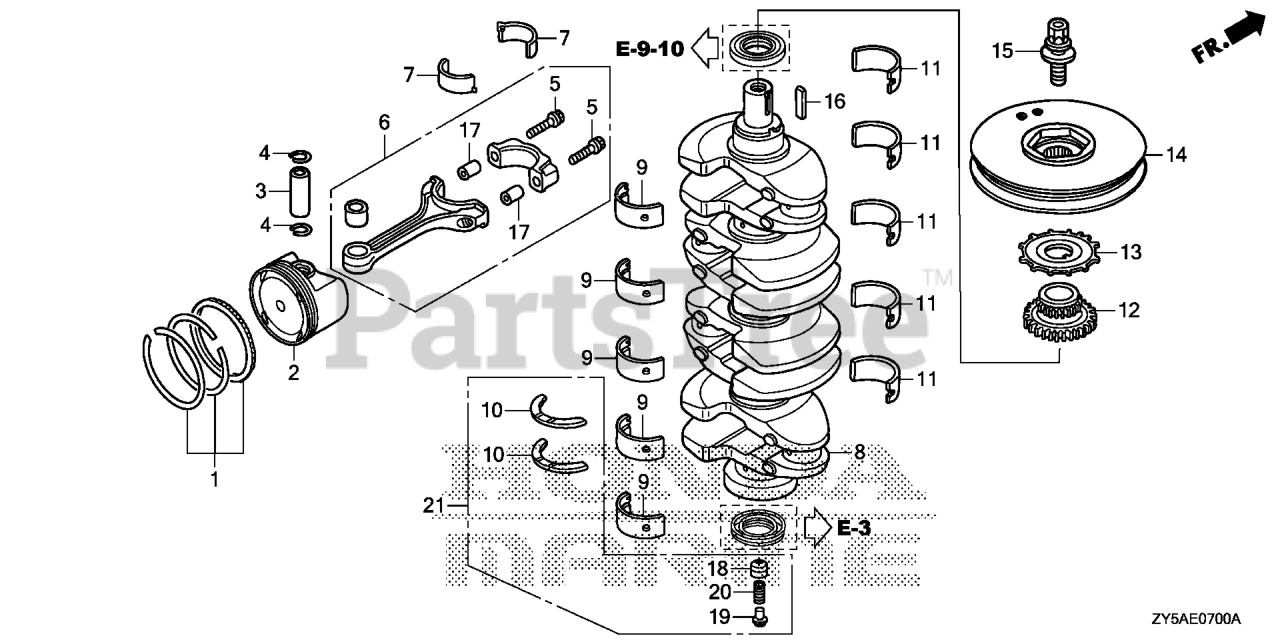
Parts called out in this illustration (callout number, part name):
1	RING SET, PISTON (STD)
3	PIN, PISTON
4	CLIP, PISTON PIN
5	BOLT, CONNECTING ROD (SOURCE: VINTAGE PARTS INC.)
6	ROD, CONNECTING
7	BEARING A, CONNECTING ROD (BLUE)
7	BEARING B, CONNECTING ROD (BLACK)
7	BEARING C, CONNECTING ROD (BROWN)
7	BEARING D, CONNECTING ROD (GREEN)
7	BEARING E, CONNECTING ROD (YELLOW)
7	BEARING F, CONNECTING ROD (PINK)
7	BEARING G, CONNECTING ROD (RED)
8	CRANKSHAFT
9	BEARING A, MAIN (UPPER) (BLUE) (DAIDO)
9	BEARING B, MAIN (UPPER) (BLACK) (DAIDO)
9	BEARING C, MAIN (UPPER) (BROWN) (DAIDO)
9	BEARING D, MAIN (UPPER) (GREEN) (DAIDO)
9	BEARING E, MAIN (UPPER) (YELLOW) (DAIDO)
9	BEARING F, MAIN (UPPER) (PINK) (DAIDO)
10	WASHER, THRUST
11	BEARING A, MAIN (LOWER) (BLUE) (DAIDO)
11	BEARING B, MAIN (LOWER) (BLACK) (DAIDO)
11	BEARING C, MAIN (LOWER) (BROWN) (DAIDO)
11	BEARING D, MAIN (LOWER) (GREEN) (DAIDO)
11	BEARING E, MAIN (LOWER) (YELLOW) (DAIDO)
11	BEARING F, MAIN (LOWER) (PINK) (DAIDO)
12	SPROCKET, CHAIN DRIVE
13	PLATE, CRANK PULSER
14	PULLEY, CRANKSHAFT
15	BOLT-WASHER (16X49)
16	KEY (4.5X21)
18	RETAINER, SPRING
19	SEAT, SPRING (150)
20	SPRING, SUPPORT
